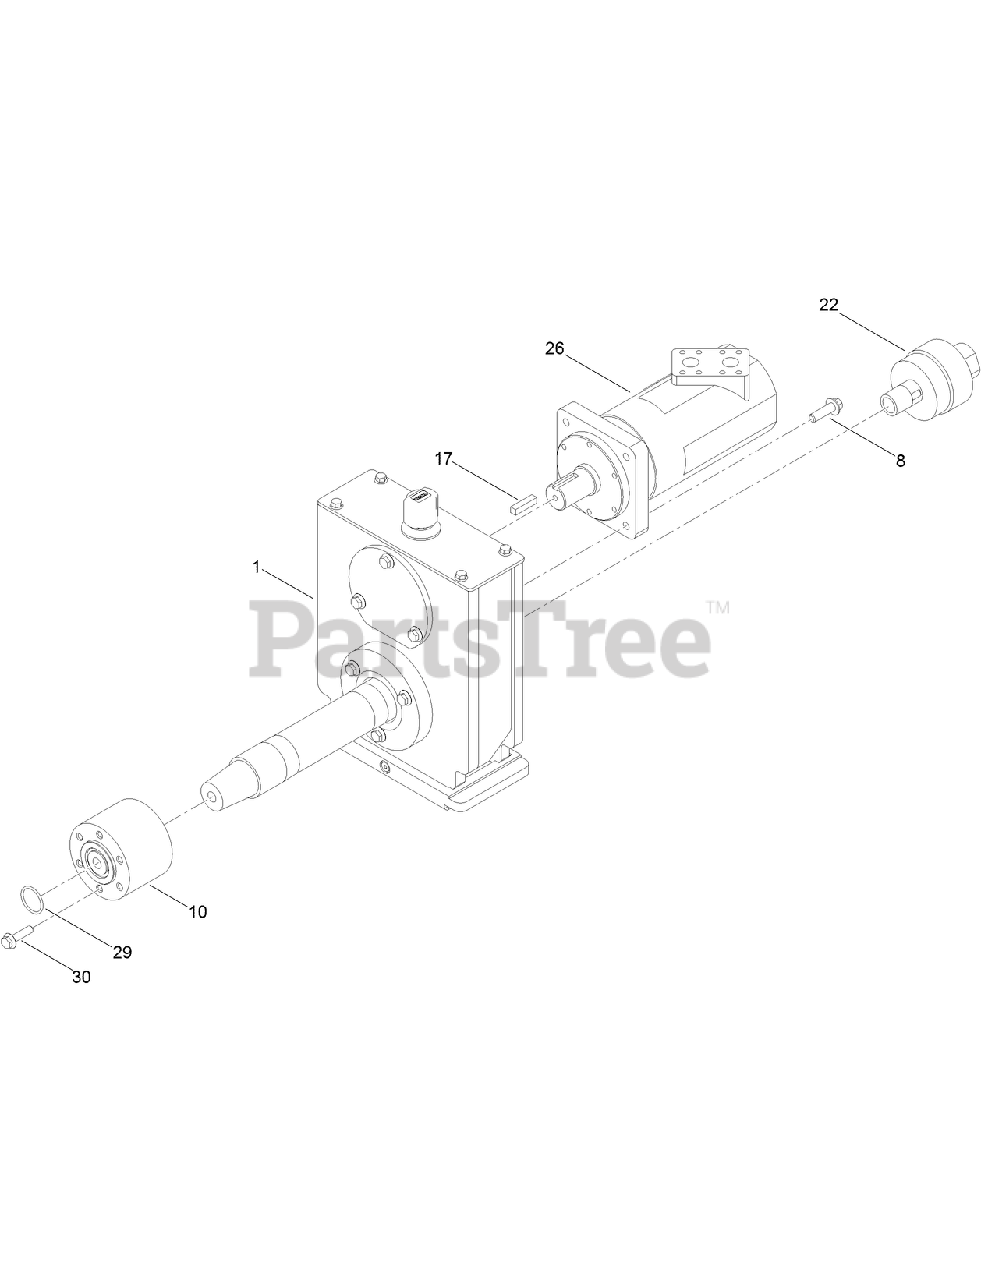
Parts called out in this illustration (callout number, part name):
1	ROTARY BOX ASM
8	SCREW-HHF
10	ADAPTER-SPINDLE
17	KEY-BOX, ROTARY
22	SWIVEL-MUD
26	HYD MOTOR ASM
29	O-RING
30	SCREW-HHF
